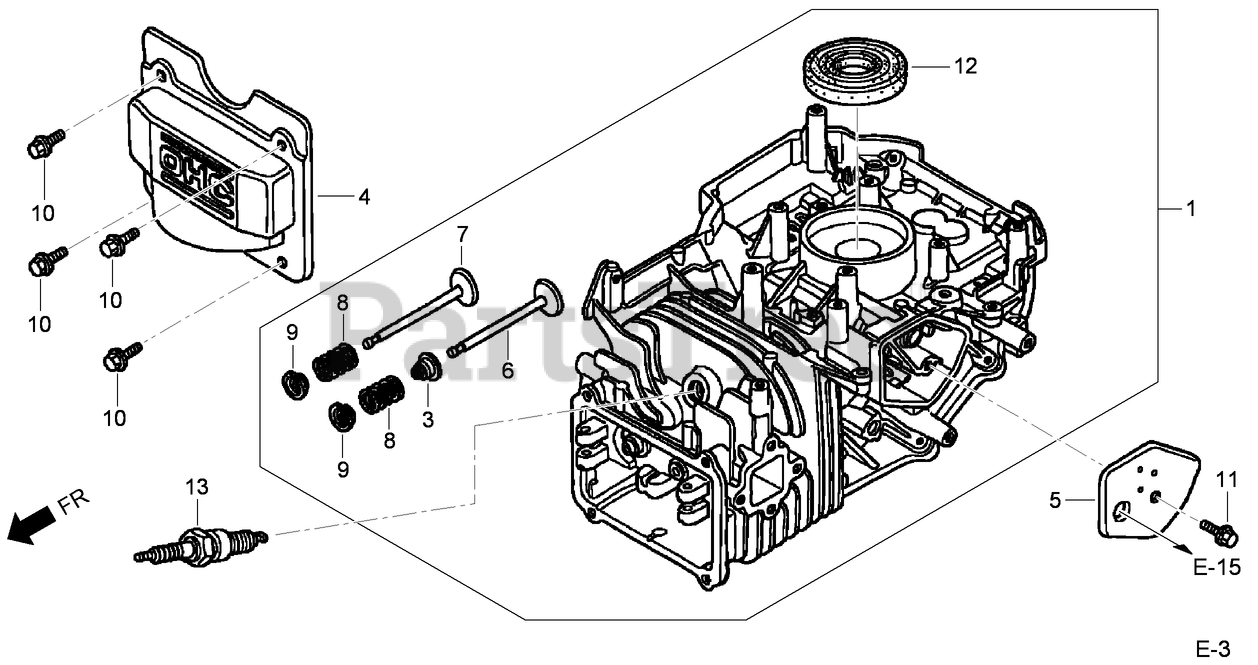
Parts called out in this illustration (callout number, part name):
1	CYLINDER ASM
3	SEAL-STEM, VALVE
4	COVER-HEAD, CYLINDER
4	COVER-HEAD
5	COVER-BREATHER (BREATHER VALVE ASM)
6	VALVE-INTAKE (ROCKNEL) (engine serial numbers up to 6330748)
6	VALVE-INTAKE (engine serial numbers starting at 6330749)
7	VALVE-EXHAUST
8	SPRING-VALVE
9	RETAINER-SPRING, VALVE
10	BOLT-FLANGE (6X12) (C T200)
11	BOLT-FLANGE (6X14) (C T200)
12	SEAL (25.4X62X6)
13	SPARK PLUG (B P R 6E S) (N G K)
